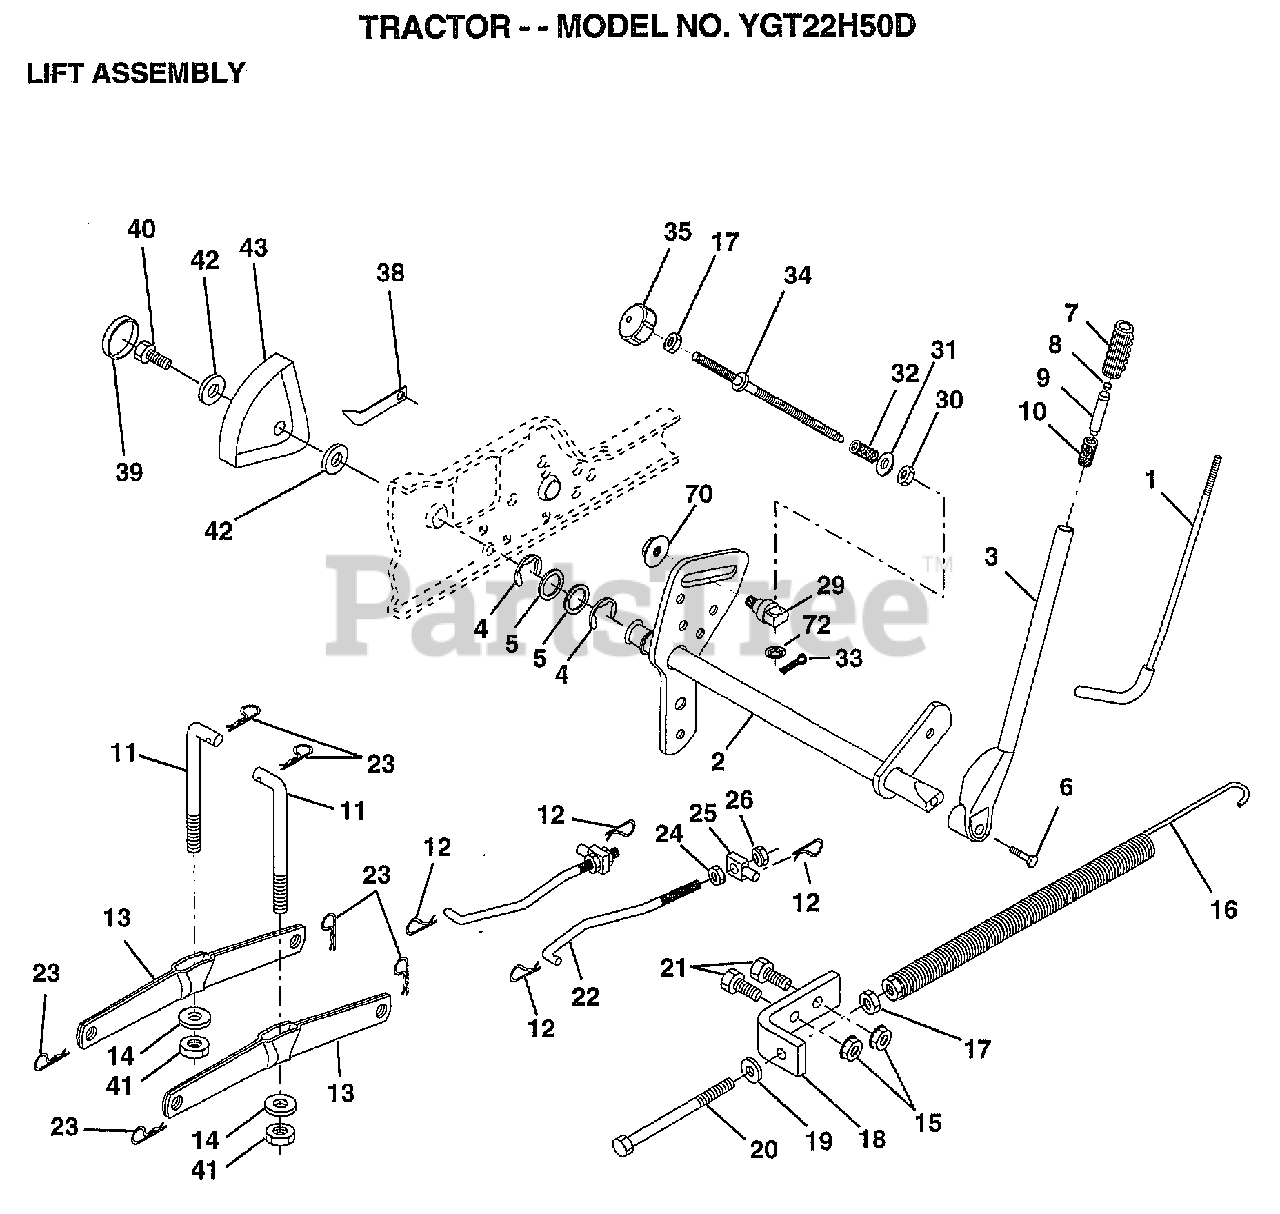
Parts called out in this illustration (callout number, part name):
1	LEVER ROD LT
2	SHAFT.ASM.LIFT.VGT
3	LEVER.ASM.LIFT.RH
4	E-RING
5	WASHER
6	"BOLT,HEX"
7	GRIP, HANDLE
10	SPRING T
11	LINK.LIFT.MWR.VGT
12	RETAINER SPRING
13	ARM SUSP REAR
14	BEARING PVT LH
17	NUT
18	BRACKET SPRING AS
19	WASHER
20	BOLT-ADJ SPRING T
21	BOLT
22	LINK.FRONT
24	NUT
25	TRUNION
26	NUT.LK.W/WSH.1/2.
29	TRUNNION
30	NUT T
31	WASHER
32	SPRING.COMP.INF.H
34	ROD.ADJ.LIFT
35	KNOB INF 3/8-16
38	POINTER HEIGHT INDICATOR
39	"PLUG,HOLE"
40	SCREW
41	NUT.CROWNLOCK.3/8
42	WASHER
43	HEIGHT INDICATOR
70	NUT.HXFLG.LOCK.
72	NUT PUSH M
